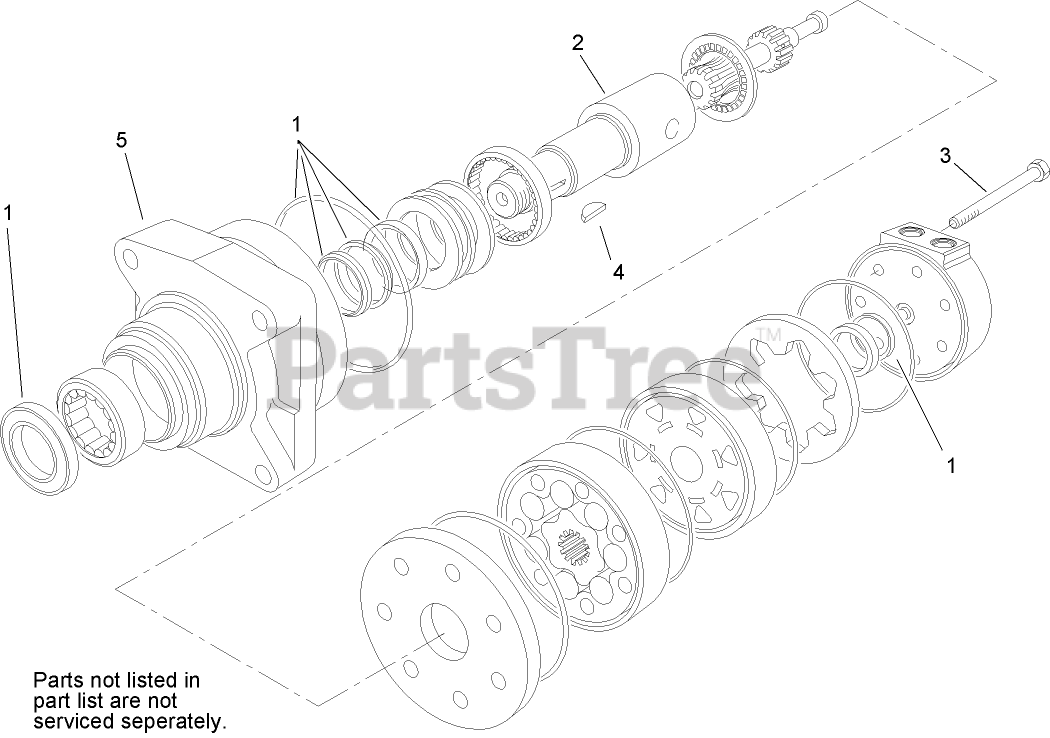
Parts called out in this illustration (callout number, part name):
1	SEAL KIT
2	COUPLING-SHAFT
3	SCREW-HH
4	KEY-WOODRUFF
5	MOTOR HOUSING ASM
